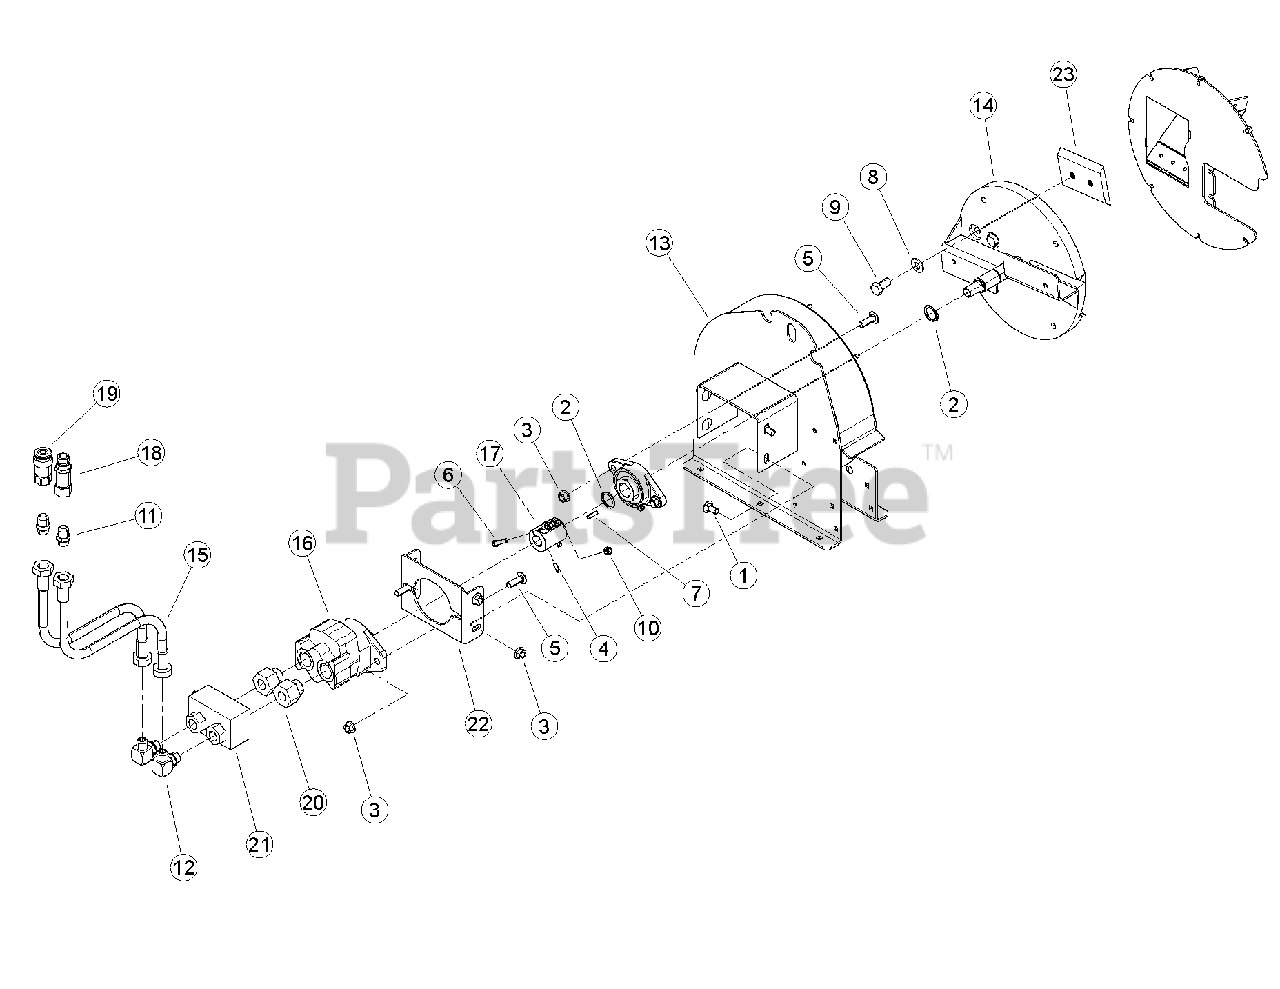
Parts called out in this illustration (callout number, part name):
1	BOLT, 1/2 X 1 CRG GR5 ZP
2	SNAP RING, 1-1/4 EXT. HEAVY DUTY
3	NUT, 1/2" SERRATED FLANGE
4	SET SCREW, 1/4 X 5/8 SQ HD
5	BOLT, 1/2 X 1-1/2 CRG SN GR5 ZP
6	BOLT, 5/16 X 1-1/2 GR5 HEX CPS ZP
7	KEY, 1/4" SQ X 1" LG
8	WASHER, 5/8 SAE HARDENED
9	BOLT, M16 X 2.0 X 30 HEX HD W/ PATCH
10	NUT, 5/16-18 NYLOCK-FLANGE
11	ADAPTER, -10 MORING/-10 MJIC
12	ADAPTER, -10 MORING/-10 MJIC 90 DEG
13	BEARING, 1-1/4" DIA 2 BOLT FLANGE
14	WELDMENT, 4-1/2 HYD ROTOR
15	HOSE,.63X-10 FMJIC SW/ -10 FMJIC SW 46"
16	MOTOR, .93 CU. IN. HYD
17	COUPLER, 7/8 SPLIT
18	COUPLER, MALE PRESSURE CONNECT
19	COUPLER, FEMALE CONNECT
20	ADAPTER, -16 MORING X -10 FMORING
21	MANIFOLD, OVERRUN AND REVERSE CHECK -10
22	PLATE, MOTOR MOUNT
23	BLADE, BIG CHIPPER
